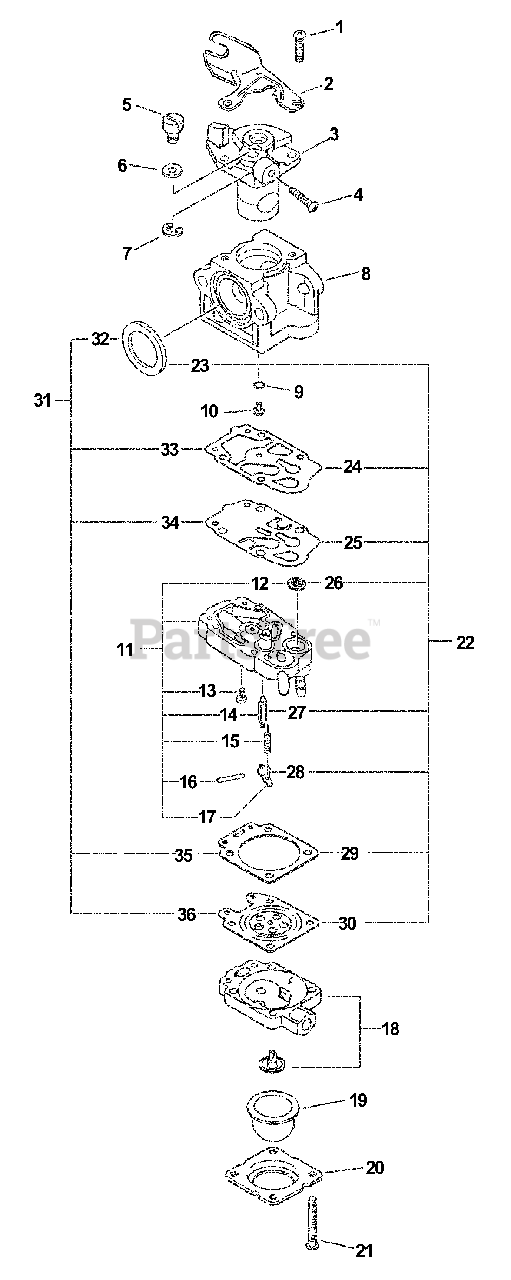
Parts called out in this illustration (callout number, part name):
2	BRACKET, CABLE
3	THROTTLE VALVE ASSY
4	SCREW, IDLE ADJUST
7	RING, RETAINING
8	BODY, CARBURETOR
11	BASE, PURGE
12	STRAINER
13	SCREW, METERING LEVER PIN
14	VALVE, INLET NEEDLE
15	SPRING, METERING LEVER
16	PIN, METERING LEVER
17	LEVER, METERING
18	PURGE BASE ASSY
19	BULB, PURGE
20	RETAINER, PURGE BULB
21	SCREW, PUMP COVER
22	REPAIR KIT
23	SEAL
24	GASKET, PUMP
25	DIAPHRAGM, PUMP
26	STRAINER
27	VALVE, INLET NEEDLE
28	LEVER, METERING
29	GASKET, METERING
30	DIAPHRAGM, METERING
31	DIAPHRAGM/GASKET KIT
32	SEAL
33	GASKET, PUMP
34	DIAPHRAGM, PUMP
35	GASKET, METERING
36	DIAPHRAGM, METERING
